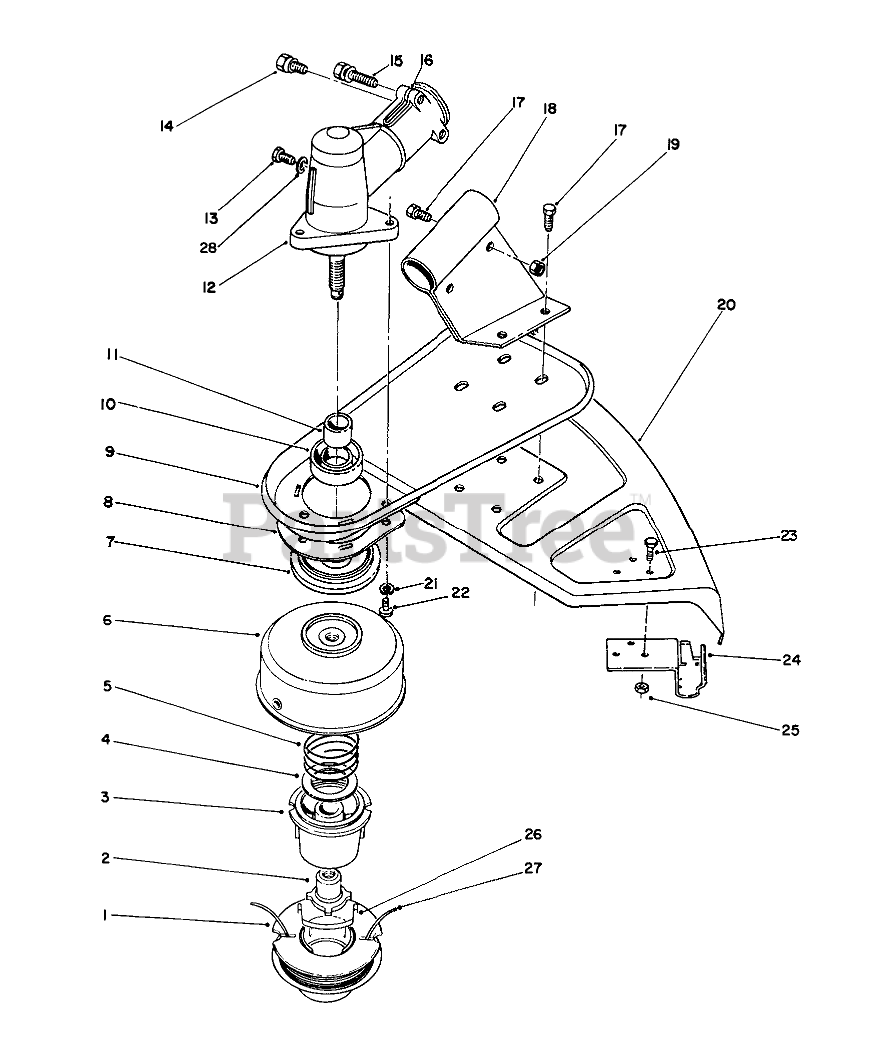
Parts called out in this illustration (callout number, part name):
1	Spool-Prewound .08 Dia. 38- (Incl. Ref. #26-27)
2	LH DRIVER
3	SPOOL CORE
4	WASHER-FLAT
5	SPRING
6	ASM - TRIMMER DRUM & EYELET
7	DUST CAP F/W
8	GRASS WRAP GUARD
9	SHIELD SUPPORT R
10	OIL SEAL
11	SPLINED SLEEVE
12	Gear Box Assembly (Incl. Ref. #10, 11, 13-16 & 28)
13	HHMS SCREW
14	HHMS SCREW
15	HHMS SCREW
16	WASHER
17	SCREW-SHH
18	SHIELD BRKT
19	NUT-LOCK, NI
20	Shield-Grass
21	LOCKWASHER
22	SCREW
23	SCREW-SHH
24	BRACKET & KNIFE ASM
25	NUT-LOCK, NI
26	SADDLE-SPOOL CAP
28	GASKET
